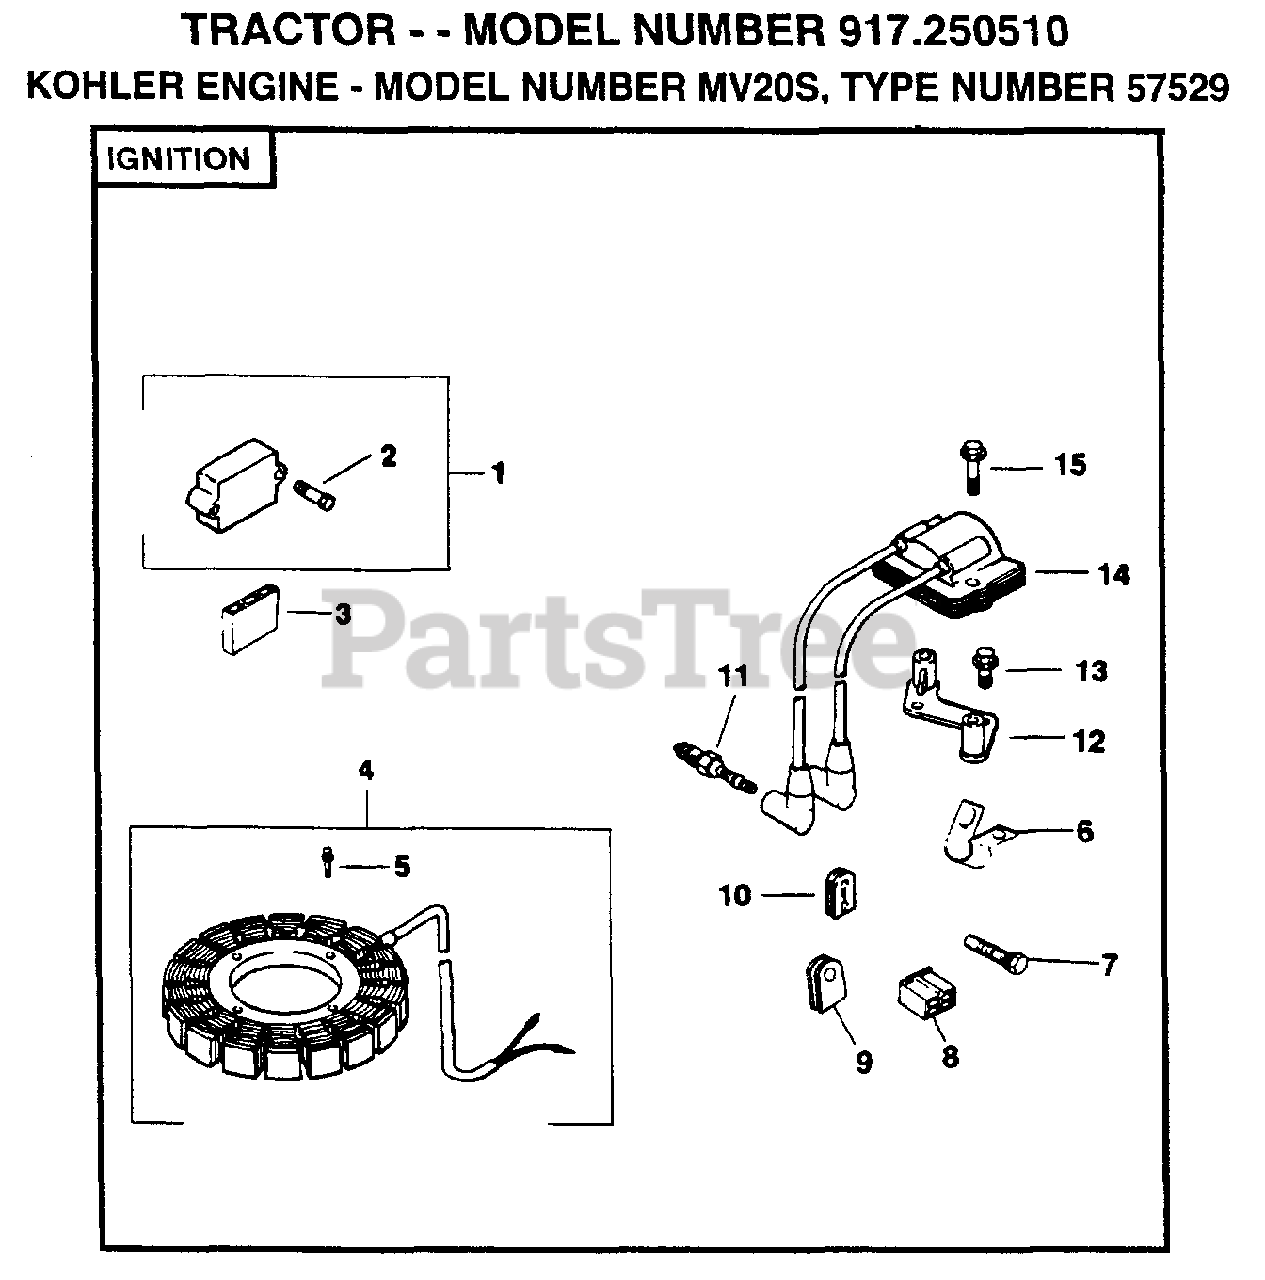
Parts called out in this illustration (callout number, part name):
2	SCREW
3	CONNECTOR
4	KIT
5	SCREW
6	CLIP
7	SCREW
9	GROMMET
13	SCREW, 1/4-20 X 1
